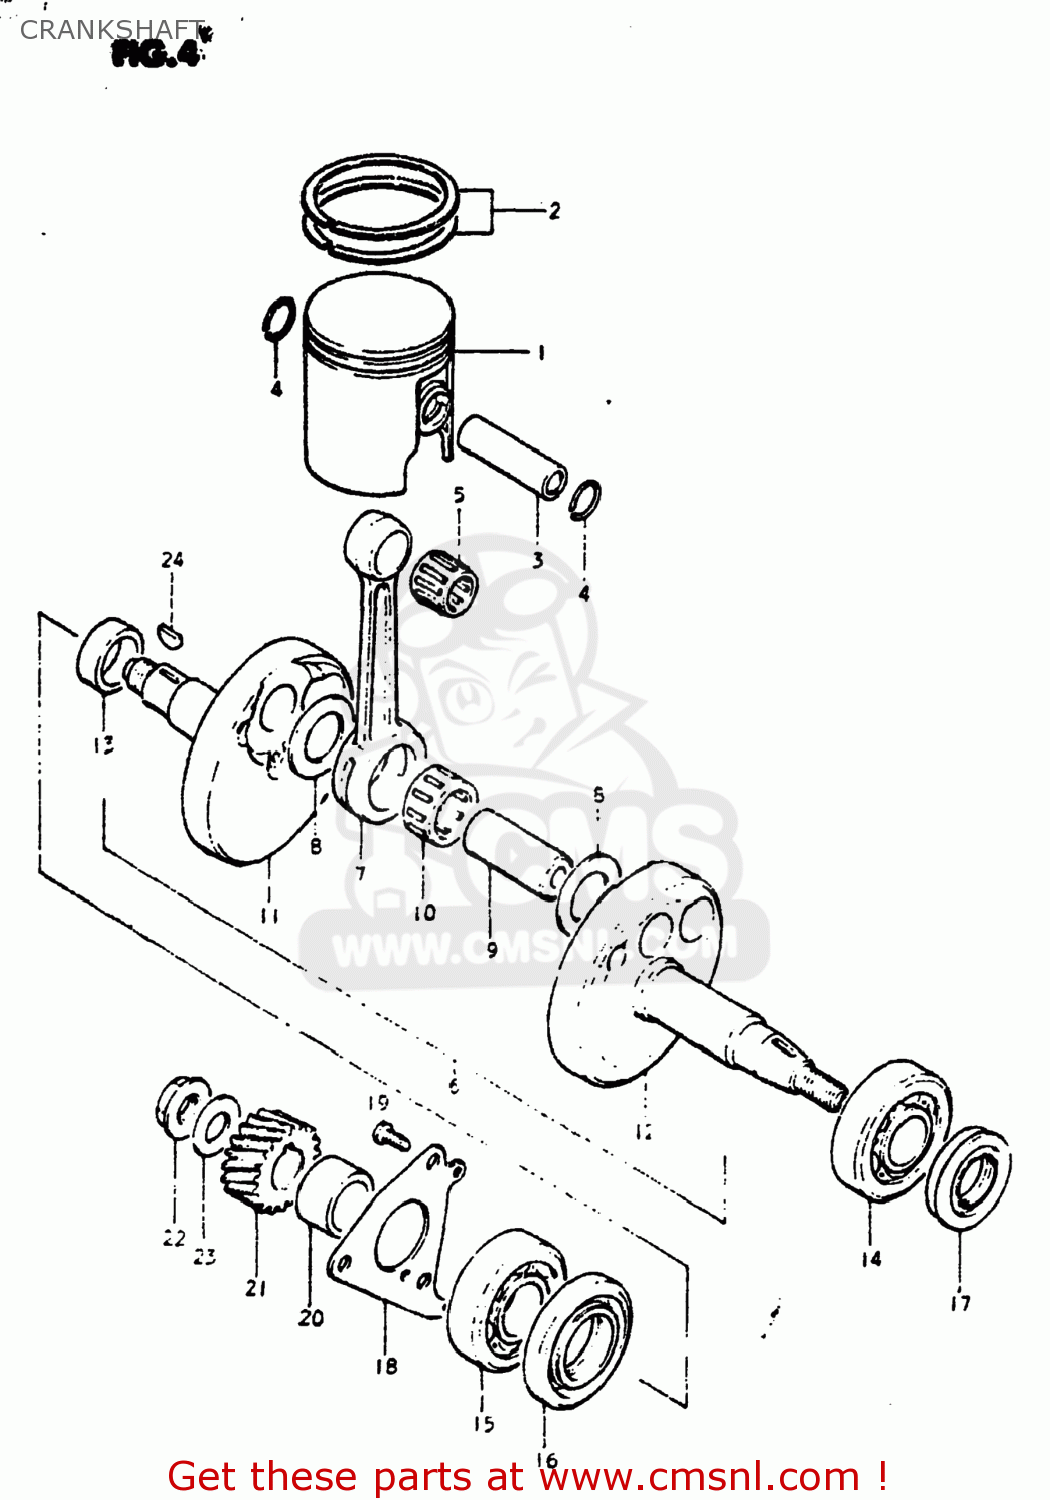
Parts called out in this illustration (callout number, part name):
1	PISTON (49.00MM)
2	RING SET,PISTON
3	PIN,PISTON
4	RING,SNAP
5	BEARING
6	CRANKSHAFT ASSEMBLY
7	ROD,CONNECTING
8	WASHER
9	PIN,CRANK
10	BEARING
11	CRANKSHAFT,RIGHT
12	CRANKSHAFT,LEFT
13	SPACER(20X26X9)
14	Bearing
15	BEARING
16	SEAL,OIL(26X47X7.3)
17	SEAL,OIL(19.6X37X8)
18	RETAINER,CRANKSHAFT BEARING,R
19	SCREW 6X12
20	SPACER(20X26X14)
21	GEAR,PRIMARY DRIVE NO.19
22	NUT
23	WASHER
24	KEY
